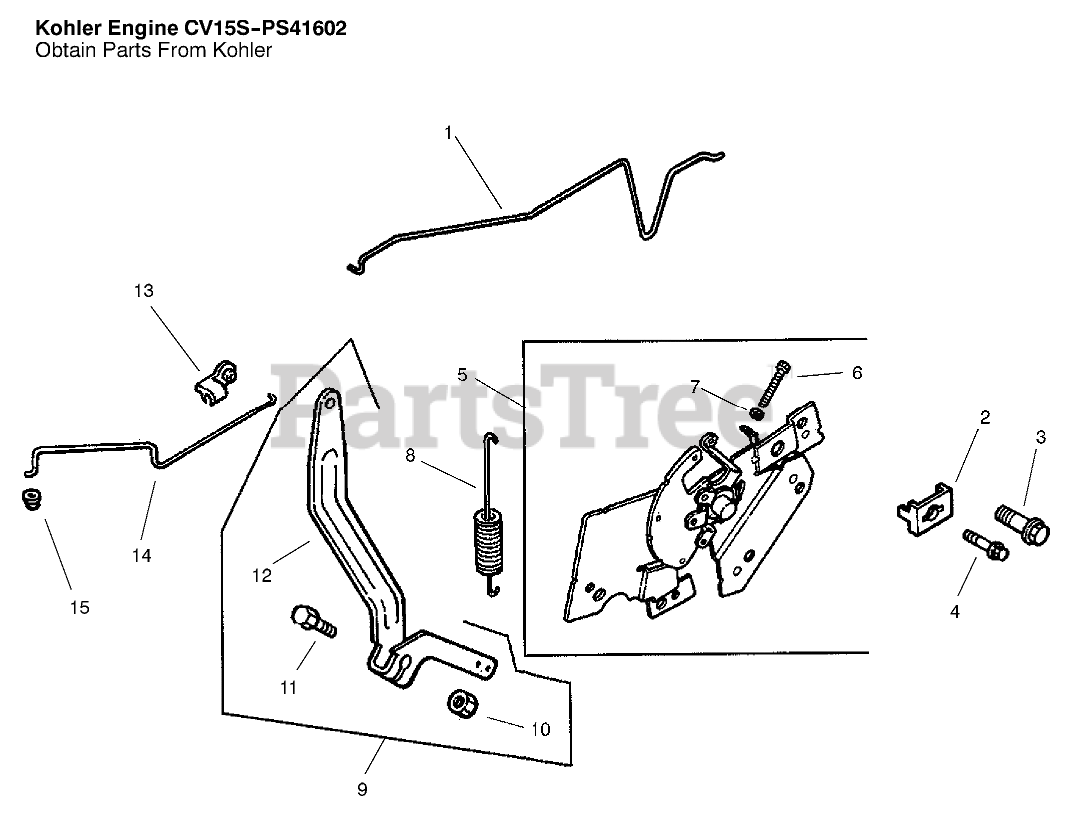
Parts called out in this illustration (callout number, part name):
1	Linkage Choke
2	Clamp
3	Screw-HHF (M5x0.8x16)
4	Screw-Lobe Socket
5	Control-Speed ASM
6	Screw-HH
7	Nut-Hex
8	Spring-Governor
9	Set-Gasket
10	Nut
11	Bolt
12	Lever-Governor
13	Bushing-Linkage
14	Linkage-Throttle
15	Bushing-Linkage
